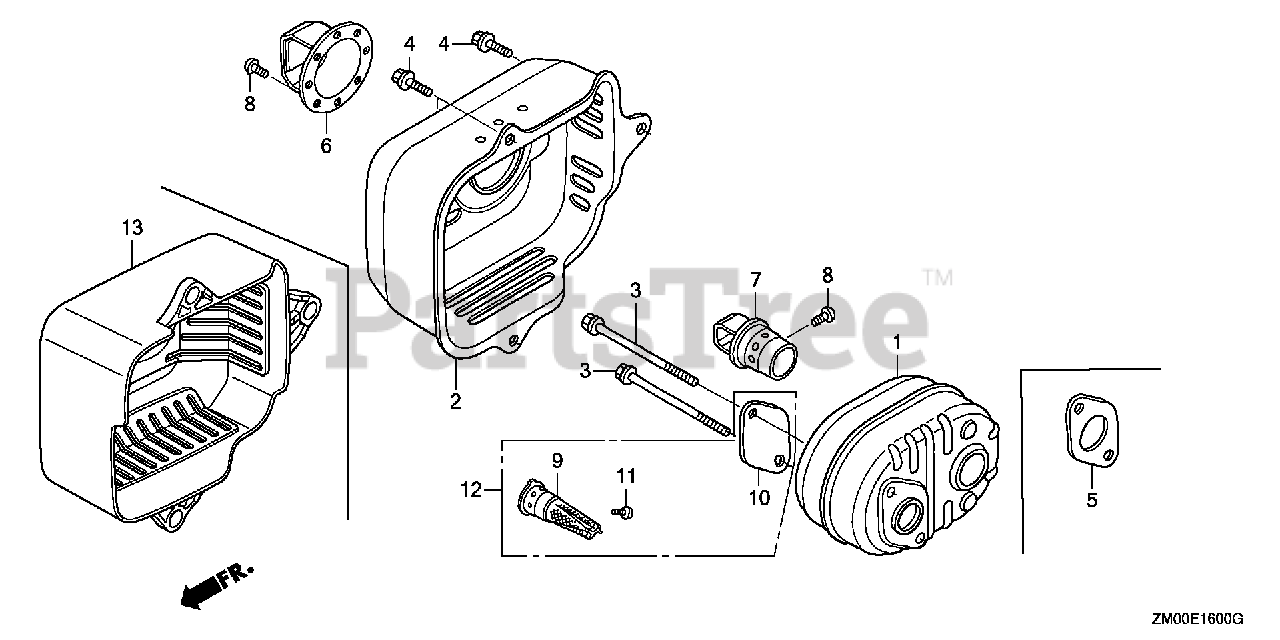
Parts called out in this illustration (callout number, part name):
2	PROTECTOR, MUFFLER
3	BOLT, FLANGE (6X79) (CT200)
4	BOLT, FLANGE (6X12) (CT200)
5	GASKET, MUFFLER
9	ARRESTER, SPARK
10	PLATE, ARRESTER NUMBER
11	SCREW, TAPPING (4X6)
12	ARRESTER KIT, SPARK
